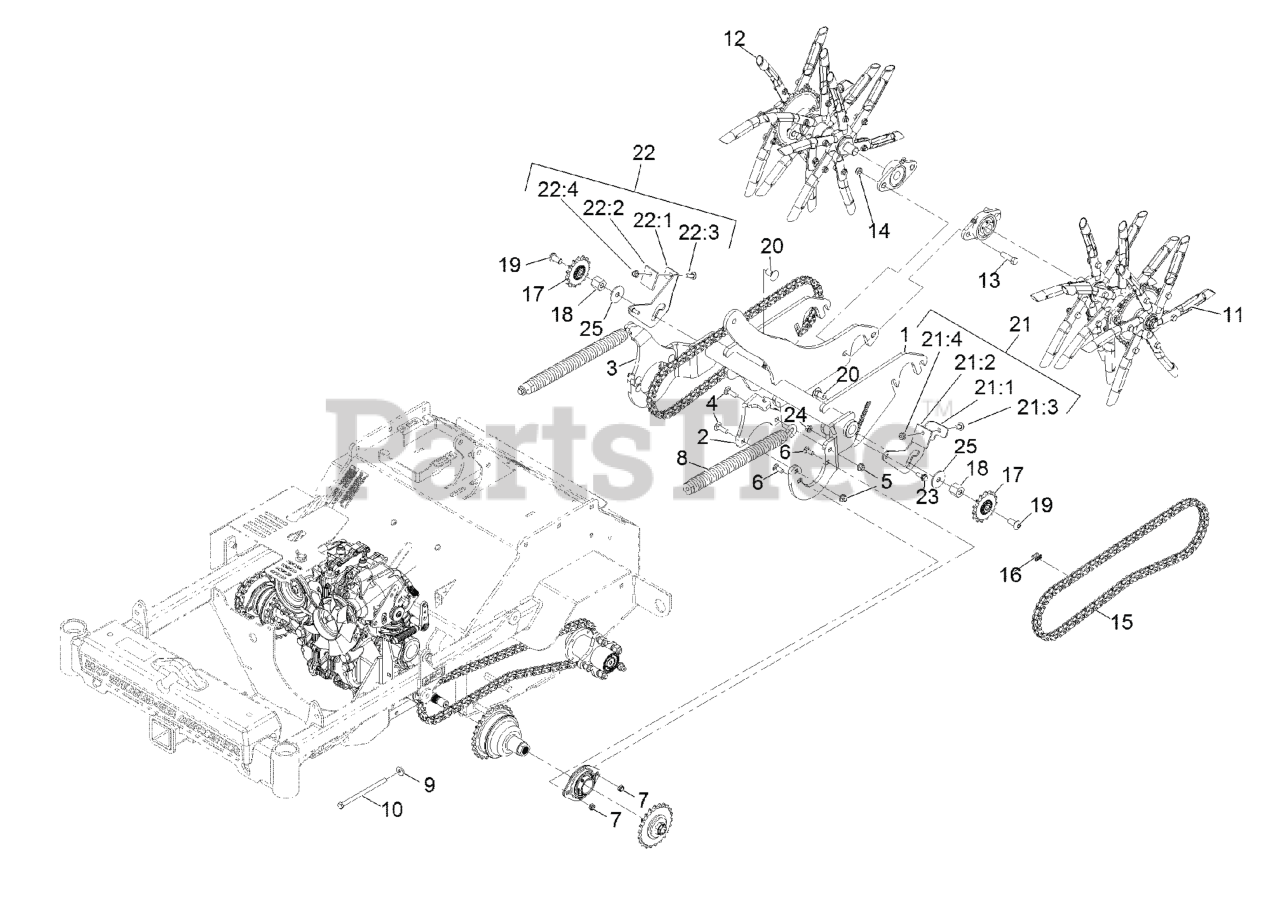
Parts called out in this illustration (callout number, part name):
1	LIFT-TINE
2	ARM-SPRING, LH
3	ARM-SPRING, RH
4	BOLT-CARR
5	NUT-HF, NI
6	BOLT-CARR
8	SPRING-EXTENSION
9	WASHER-BELLEVILLE
10	BOLT-TAP, HH
11	LH TINE WHEEL ASM
12	RH TINE WHEEL ASM
14	NUT-LOCK
15	CHAIN-ROLLER
16	LINK-CONNECTING
17	SPROCKET-IDLER, 15T
19	SCREW- PAN SOCKET HEAD
20	SCREW-CARR
21	LH DEBRIS DEFLECTOR ASM
21:1	BRACKET-DEFLECTOR, DEBRIS
21:2	DEFLECTOR-DEBRIS
21:3	BOLT-CARR
21:4	NUT-HF, NI
22	RH DEBRIS DEFLECTOR ASM
22:1	BRACKET-DEFLECTOR, DEBRIS
22:2	DEFLECTOR-DEBRIS
22:3	BOLT-CARR
22:4	NUT-HF, NI
23	SCREW-SHOULDER
24	NUT-HF, NI
25	WASHER-FLAT
